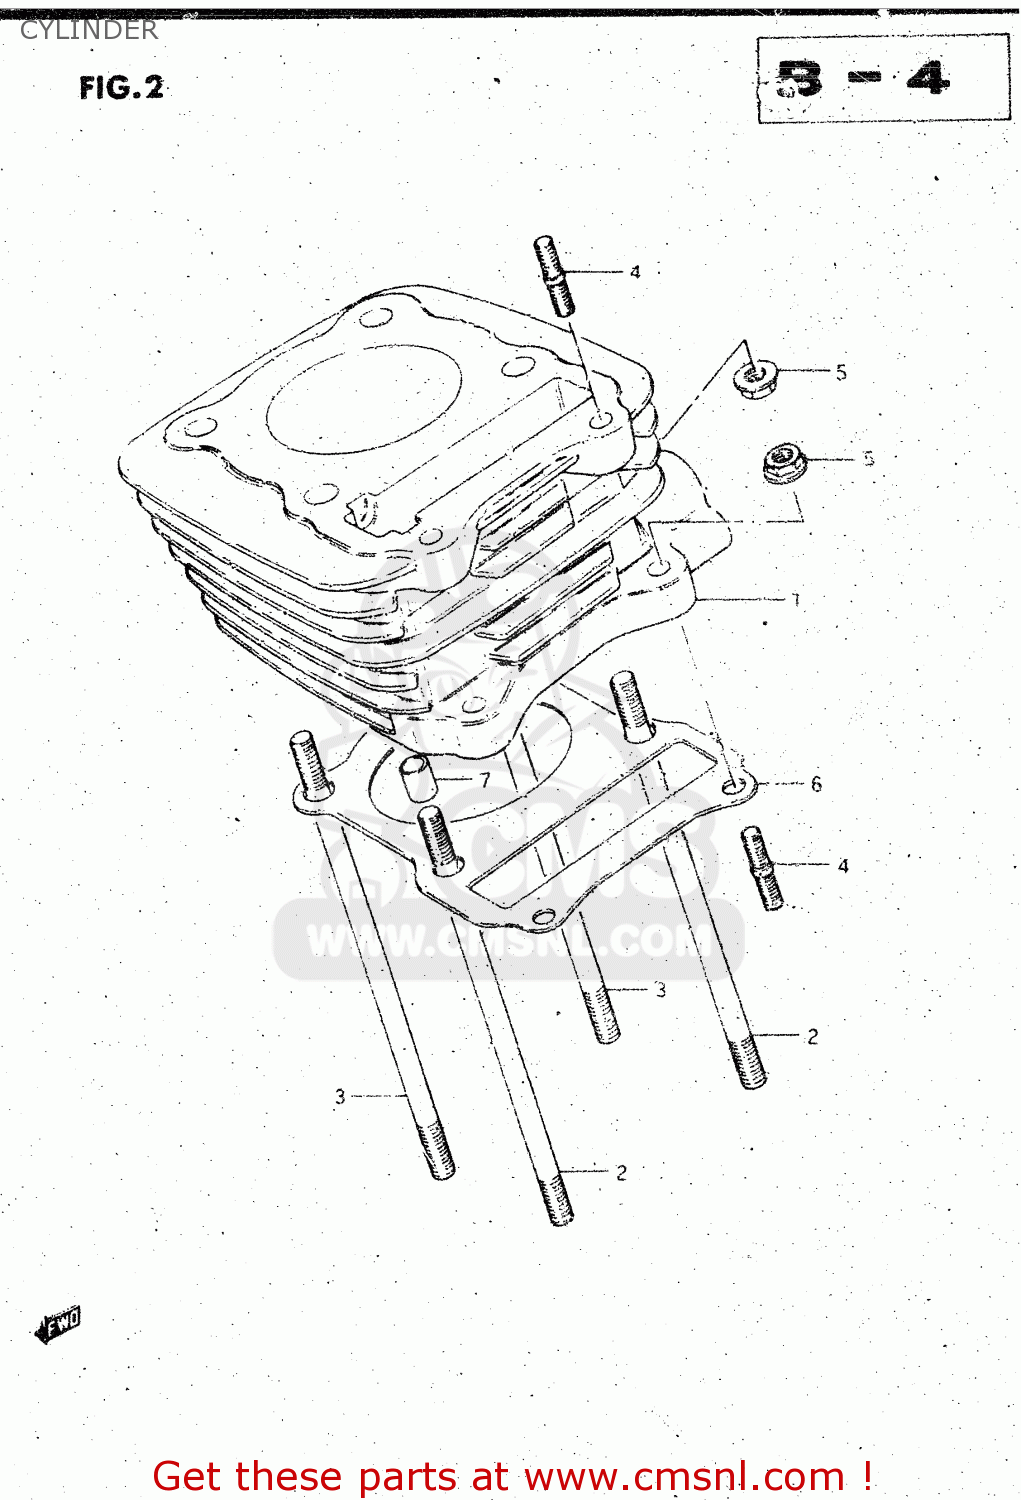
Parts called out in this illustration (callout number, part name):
1	CYLINDER
2	BOLT,STUD
3	BOLT,STUD
4	STUD 6X25
5	NUT
6	GASKET, CYLINDER
7	PIN
